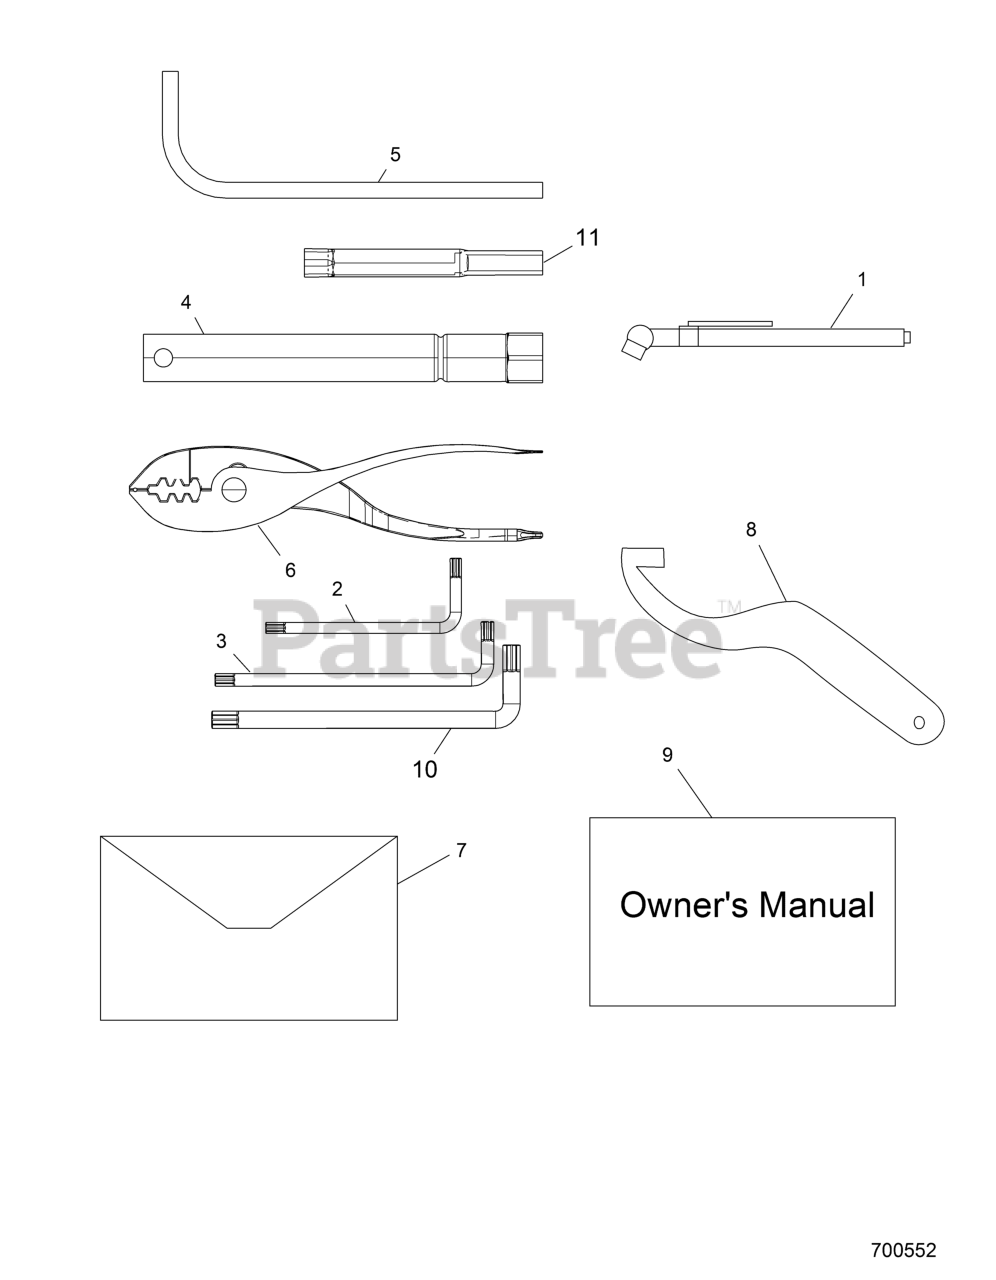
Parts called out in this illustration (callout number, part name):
1	GAUGE-TIRE PRESSURE,30 PSI
2	WRENCH-TORX,T-25
3	SOCKET-SPARK PLUG,14/16MM
4	SOCKET-SPARK PLUG,14/16MM
5	SOCKET-SPARK PLUG
6	PLIERS-COMBO, #2 ASSEMBLY
7	POUCH,TOOLKIT,9"
8	WRENCH-SPANNER, CAM
9	MAN-OWN,20 ARNS/CREW,1K
10	WRENCH-TORX,T-40
11	HANDLE, SPARK PLUG
